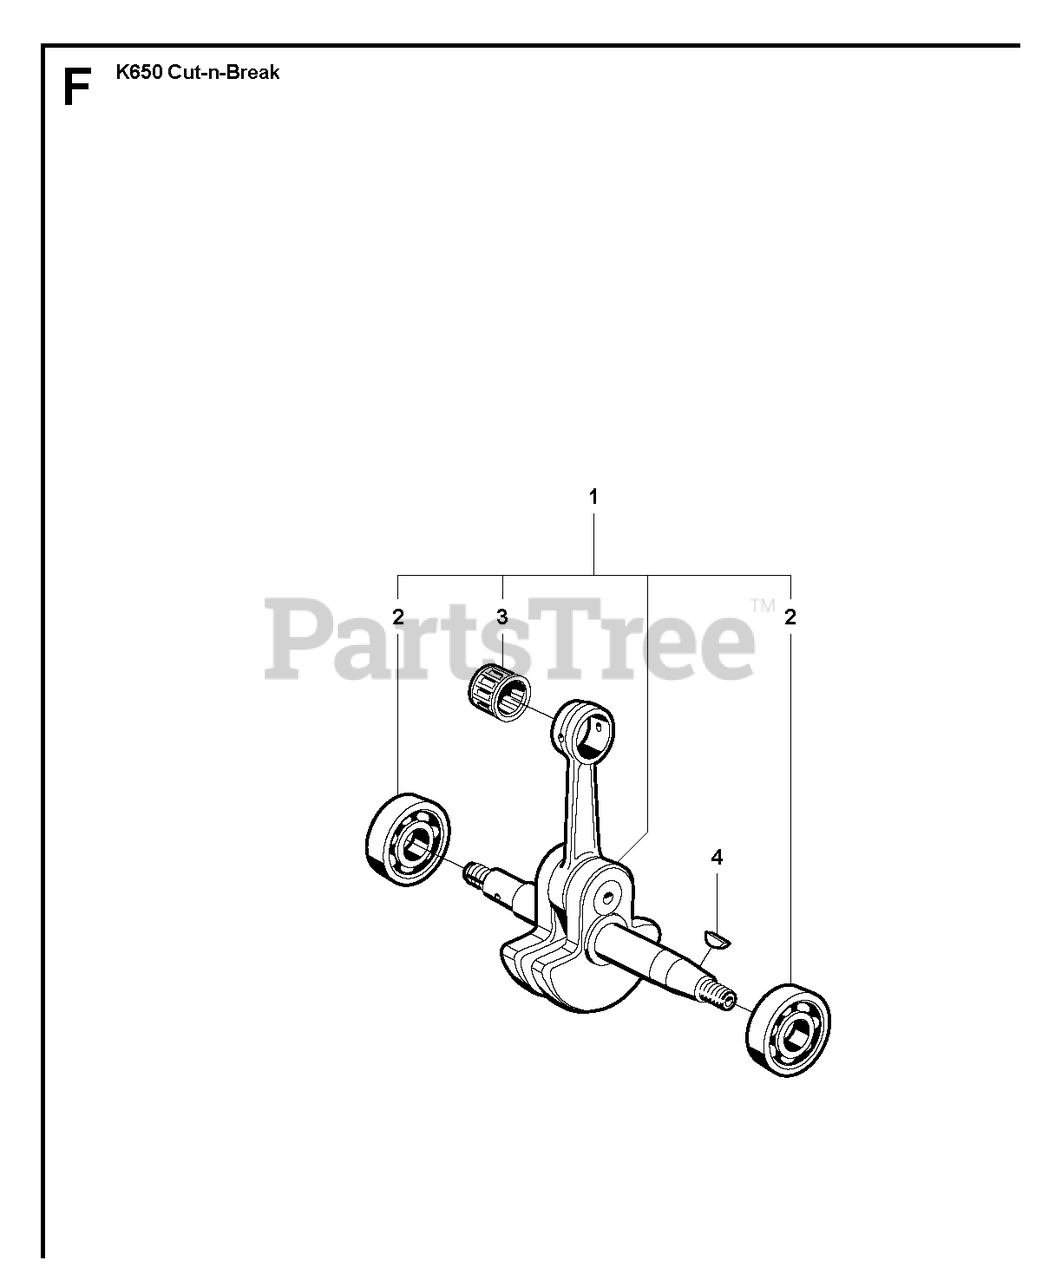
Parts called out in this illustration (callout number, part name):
1	CRANKSHAFT ASSYIncl. 2, 3
2	BALL BEARING
3	NEEDLE BEARING
4	WOODRUFF KEY
